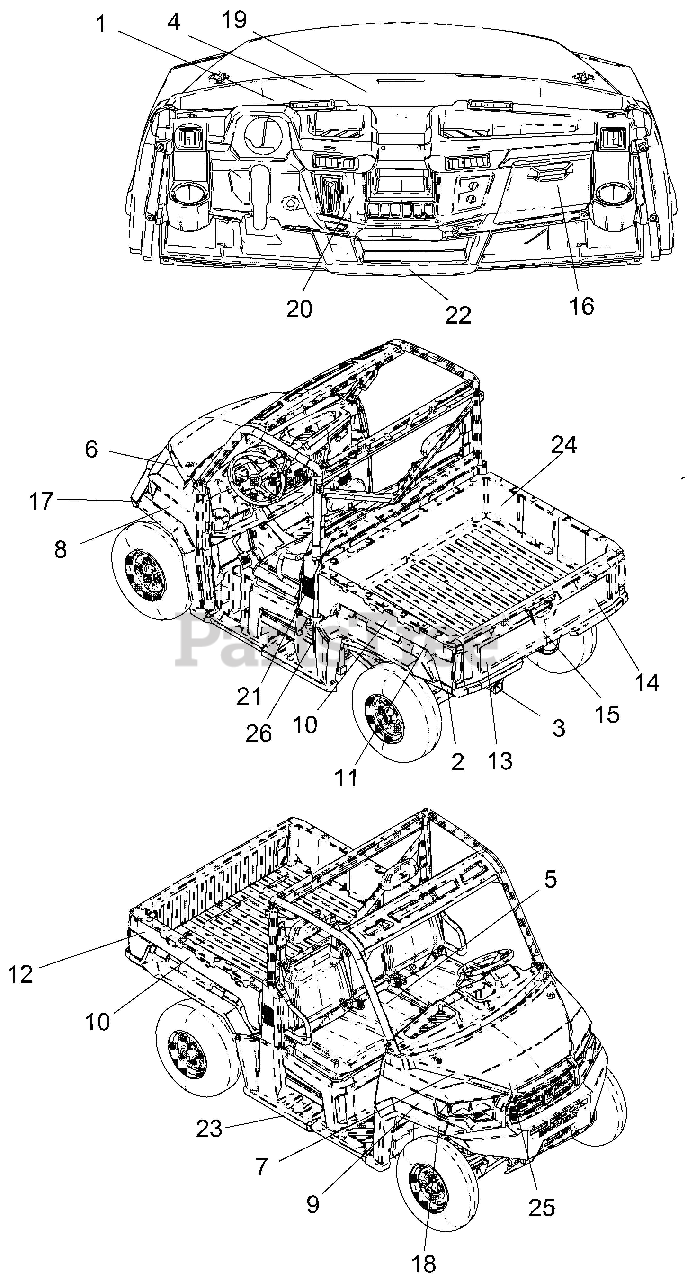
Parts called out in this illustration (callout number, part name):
1	DECAL, AGE WARNING 16
2	DECAL, REFLECTOR RED
3	DECAL, WARNING TRAILER LOAD
4	LABEL, OPEI COMPLIANCE
5	DECAL, WARNING, PULLEY
6	DECAL, HOOD TOP DIESEL LH
7	DECAL, HOOD TOP DIESEL RH
8	DECAL, HOOD SIDE ATLAS LH
9	DECAL, HOOD SIDE ATLAS RH
10	DECAL, BOX SIDE GRAVELY
11	DECAL, BOX SIDE JSV 6000 LH
12	DECAL, BOX SIDE JSV 6000 RH
13	DECAL, TAILGATE ATLAS LH
14	DECAL, TAILGATE AWD RH
15	DECAL, TAILGATE GRAVELY CENTER
16	DECAL, GLOVEBOX COVER
17	DECAL, REFLECTOR AMBER LH
18	DECAL, REFLECTOR AMBER RH
19	DECAL, WARNING DISC GRAVELY
20	DECAL, CAUTION SHIFT/BRAKE
21	DECAL, ROPS, 6000
22	DECAL,WARNING PASS/TIRE PRESS
23	DECAL NOT A STEP
24	DECAL - WARN, FUEL TRANSPORT
25	DECAL - COOLANT
26	DECAL, DIESEL FUEL ONLY
